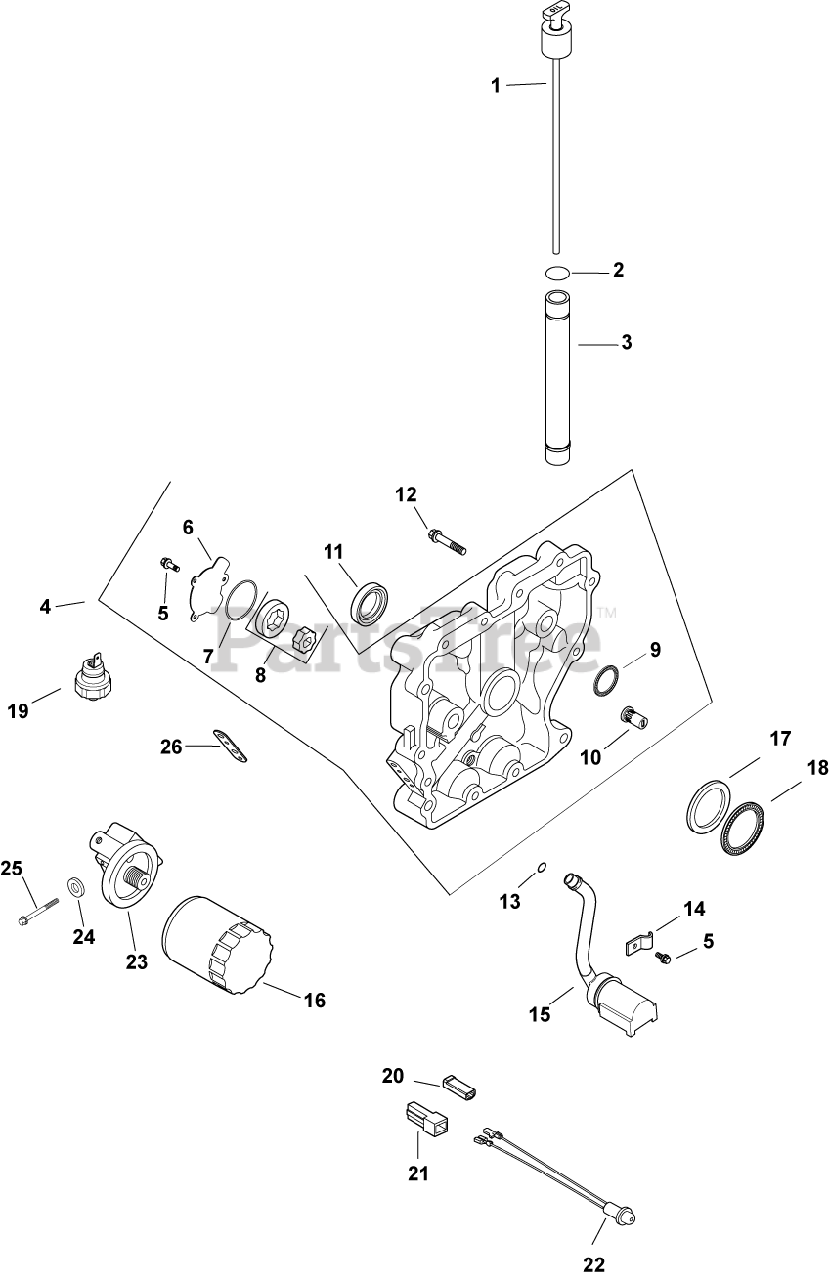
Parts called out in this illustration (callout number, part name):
3	KIT, OIL FILL TUBE - METAL
5	SCREW,FLG THD FRM M5X0.8X16-(#25086398S)
6	COVER, OIL PUMP
7	O-RING (1.78" DIA)
8	PUMP ASSEMBLY, OIL
9	BEARING, CRANKSHAFT
10	VALVE, OIL PRESSURE RELIEF
11	SEAL, OIL
12	SCREW, FLG M8X1.25X45
13	O-RING (.5" DIA)
15	KIT, OIL PICK-UP
16	OIL FILTER
17	WASHER, THRUST (1MM)
18	BEARING, THRUST
19	SWITCH, PRESSURE (CLOSED)-USE 25 099 27-
20	CONNECTOR (1 CONTACT)
21	CONNECTOR
23	ADAPTER - DISCONTINUED
25	SCREW, FLG M6X1.0X60
26	GASKET, OIL FILTER ADAPTER
